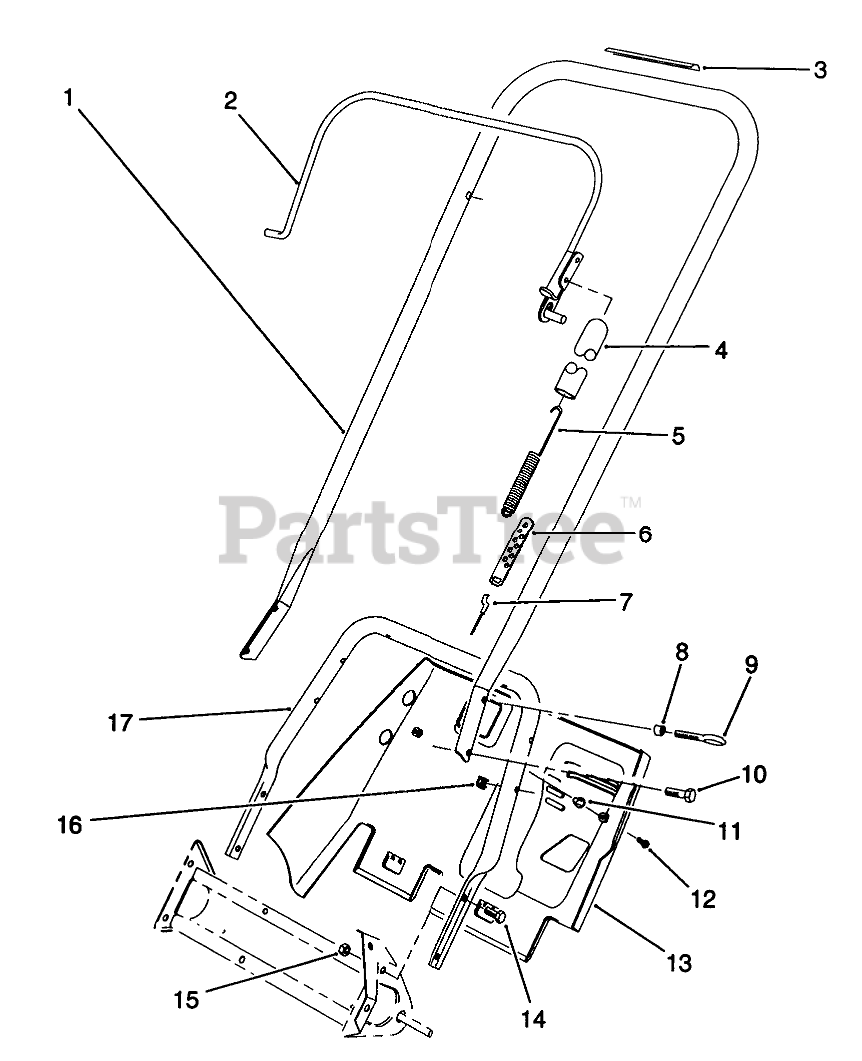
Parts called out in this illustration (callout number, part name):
1	Handle-Upper
2	Bail
3	DECAL - ROTOR DRIVE
4	COVER-SPRING
5	SPRING-CLUTCH
6	ADJUSTER-CABLE, CLUTCH
7	Cable-Clutch
8	SPACER-BLADE, ROTOR
9	EYEBOLT
10	SCREW-HEX HD SLOT
11	EXPANSION TYPE FASTENER
12	SCREW-SHWH, THREAD FORMING
13	LOWER SHROUD
14	SCREW-HH
15	NUT-LOCK, NI
16	TINNERMAN NUT
17	Handle-Lower
